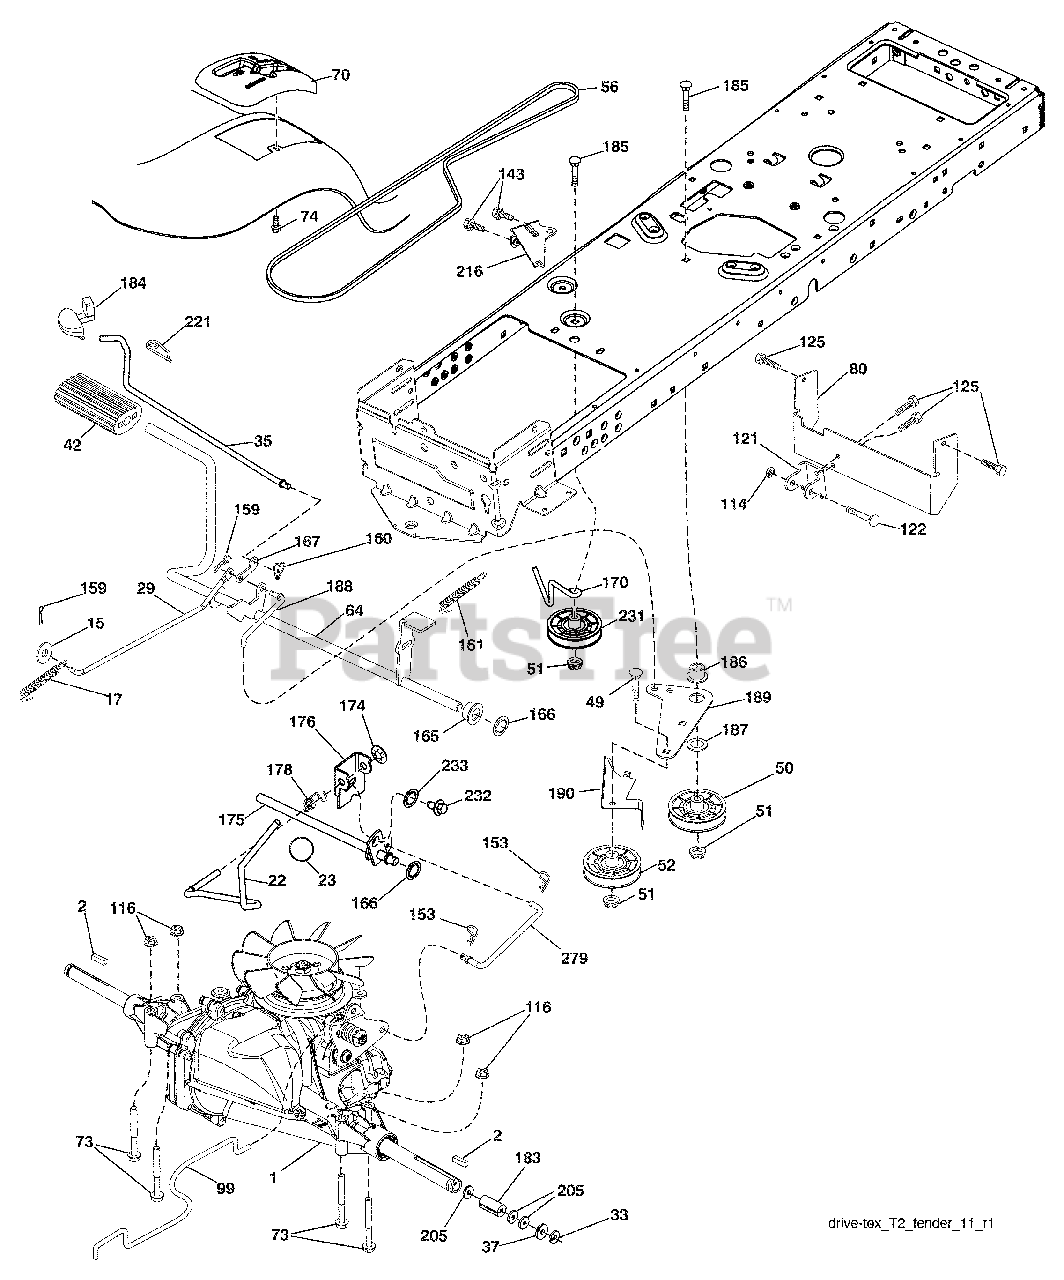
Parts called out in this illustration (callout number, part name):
2	Key Square
15	Washer 13/32 x 13/16 x 16 Ga.
17	Spring, Brake
29	Rod, Brake
35	Rod, Brake, Park
37	Washer 25/32 x 1-1/4 x 16 Ga.
42	Cover, Foot Pedal
50	Pulley Idler Flat
51	Lock Nut 3/8-16
52	Idler V-Groove 910" Offset
56	V-Belt, Drive
64	Shaft Asm. Pedal Brake Control
70	Console
73	Bolt Hex 5/16-18 Gr. 5
74	Screw 1/4 x 1/2
80	Strap Torque
99	Rod Spring Bypass
114	Nut Lock 5/16-18 unc
116	Nut Lock Hex Flange 5/16-18
121	Bracket Strap Torque
122	Bolt 5/16-18 x 2.50
125	Screw 5/16-18 x 3/4
143	Screw THDROL 5/16-18
153	Retainer Spring 1"
159	Pin Cotter 1/8 x 3/4
160	Retainer Clip
161	Spring, Return, Clutch
166	Nut Push .625
167	Latch Brake Parking
170	Keeper Belt Centerspan
175	Shaft Asm Shift
176	Arm Clevis Rod Shift
178	Spring Shift
183	Spacer Axle
184	Handle Parking Brake
186	Spacer Retainer
187	Washer
188	Link Clutch Ground Drive
189	Bellcrank Ground Drive
190	Keeper Bellcrank Ground Drive
205	Washer 25/32 x 1-5/8 x 16 Ga.
216	Bracket Pulley Idler
221	Retainer Spring Clip Handle
231	Idler V-Groove 1.688" Offset
232	Bolt 7/16-14 x 1 Gr 5
233	Washer Serrated
279	Link Shift
